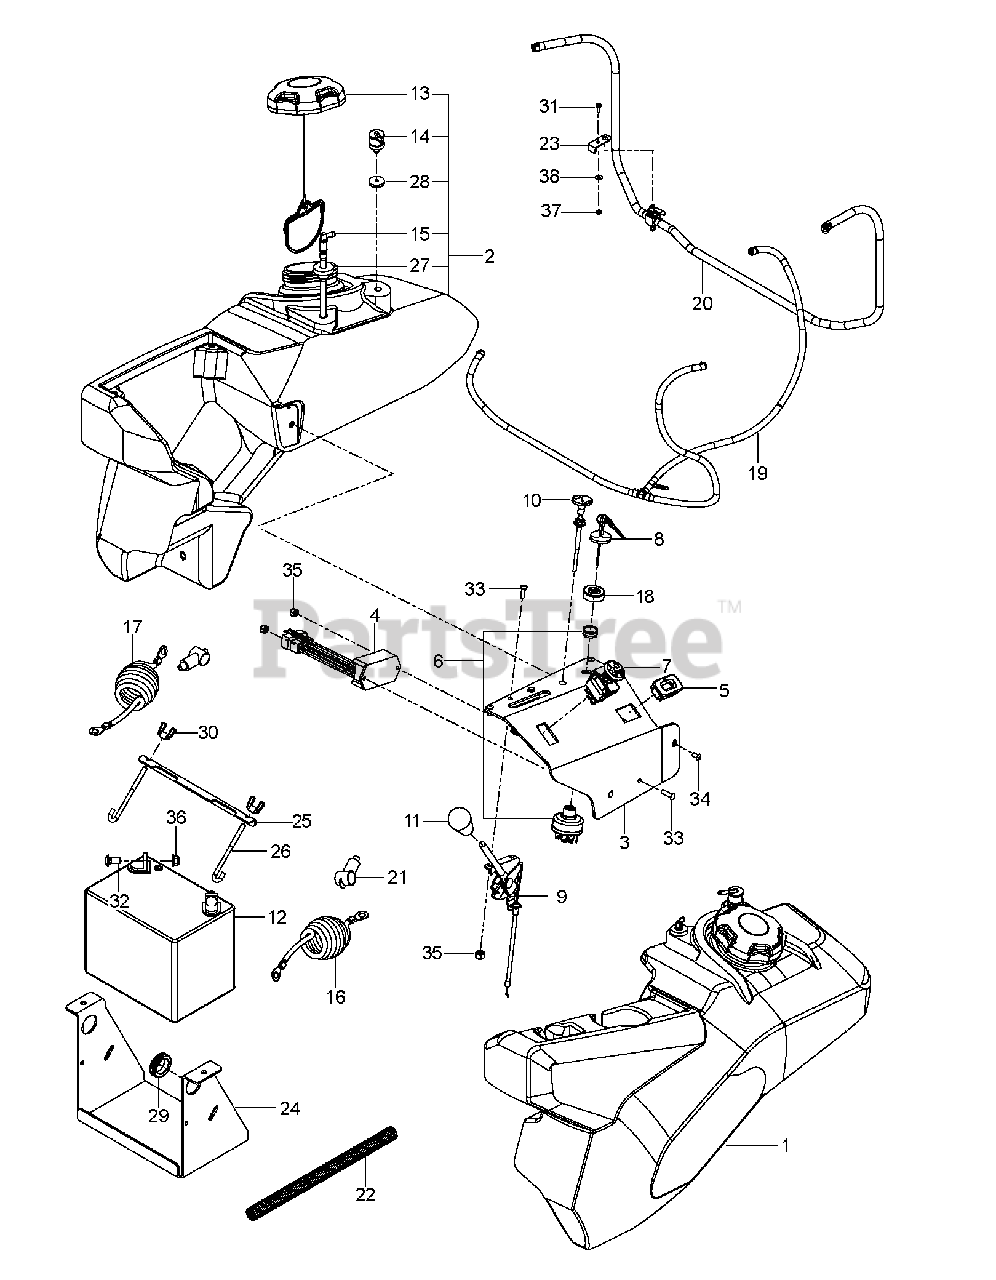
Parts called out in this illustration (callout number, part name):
1	Fuel Tank Assembly, Large LH
2	FUEL.TANK.ASM.RH.PZ.GRY.17
3	PANEL.CONTROL.GAS.GRAY
4	TIMER, SEAT
5	GUAGE.SRVCMNDR.HRMTR.
6	SWITCH, IGNITION, INDAK
7	RP SWITCH.PTO.TERMINAL.STD.RED
8	KEY, IGNITION
9	CABLE, THROTTLE, 60"
10	CABLE, CHOKE, 48"
11	KNOB - SHIFT
12	BATTERY, 12 V 330 AMP
13	CAP, FUEL
14	VALVE.FUEL.CHECK
15	FITTING, FUEL
16	CABLE, POSITIVE, 55"
17	CABLE, NEG, 55"
18	CAP IGNITION NUT
19	HOSE.ASM.VAPOR.LINE.21-30-39
20	ASSEMBLY, FUEL LINE
22	LOOM, SPLIT, CONVOLUTED
23	BRACKET.VALVE.PNT.BLACK.X431
24	BRACKET, BATTERY, BLK
25	BRACKET.BATTERY.MOUNT.PLATED
27	RUBBER GROMMET
28	GROMMET, CHECK VALVE
29	RUBBER GROMMET
30	WING NUT 1/4
31	HCS 1/4C X 3/4 HCS
32	BOLT 5/16-18 X3/4 ZN/YEL GR 5
33	SCR #10-24 X .75 SKT HD BLK
34	SCR #10-24 X 3/8 SKT HD BLK OX
35	NUT 10-24 NYLOC
36	5/16-18 NYLOC FLANGE NUT
37	JAM NUT 1/4C (2 2 PW01)
38	WASHER 1/4 FLAT
